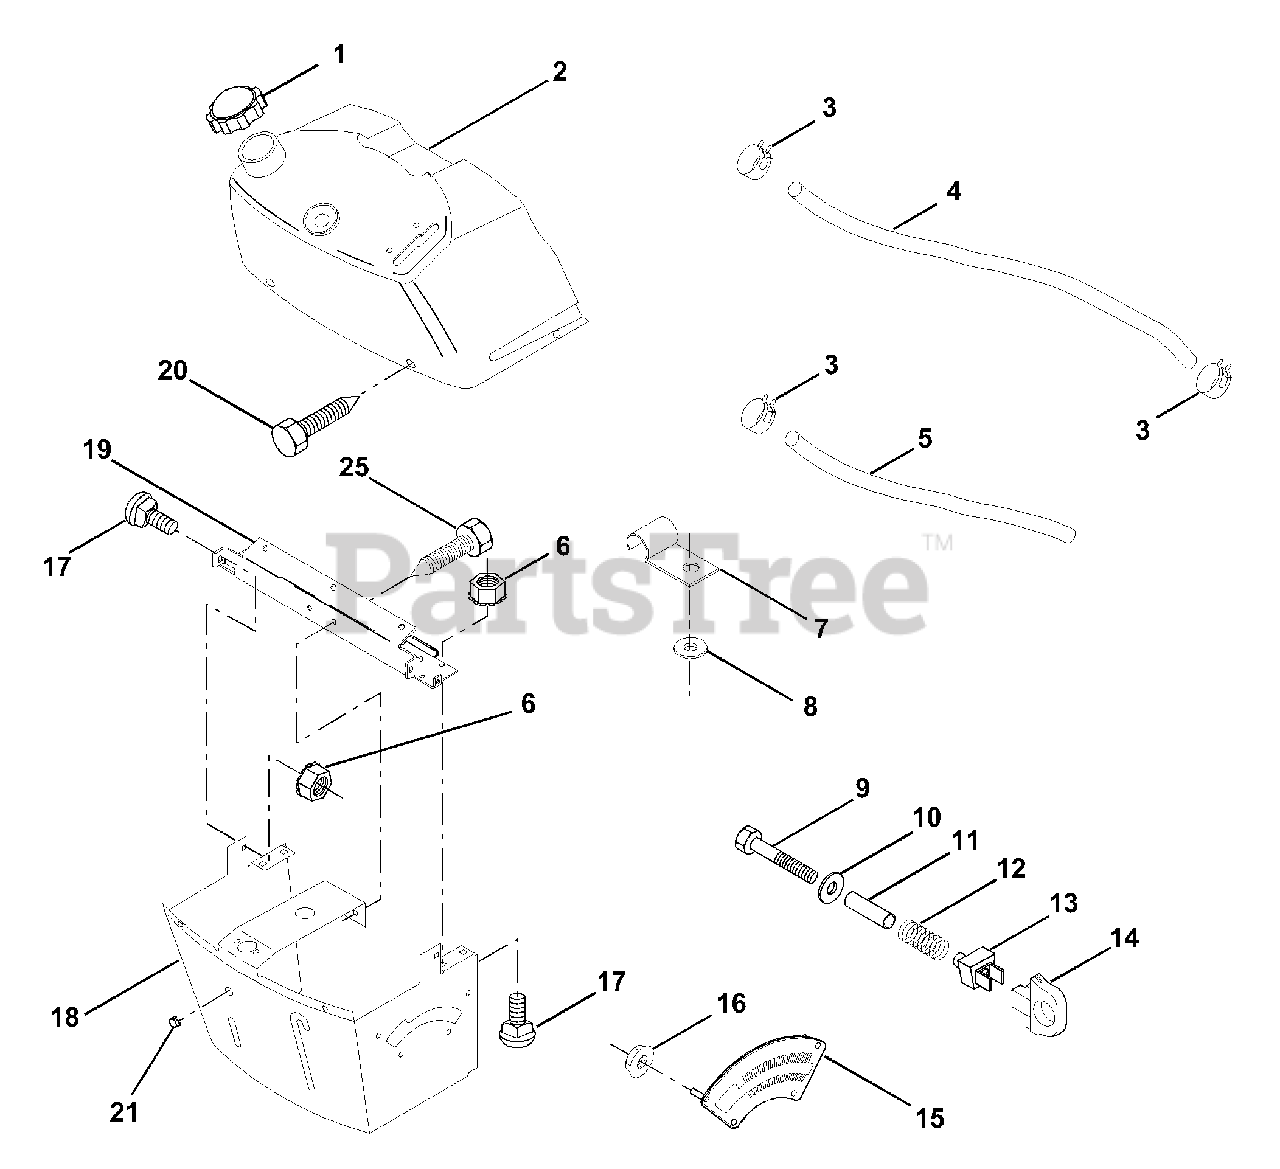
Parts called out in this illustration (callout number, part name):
2	Assembly, Dash & Fuel Tank
3	Clamp, Hose
4	Line, Fuel
5	Line, Fuel
6	Nut, Hex, Keps 1/4-20
7	Clip, Fuel Line
8	Washer 9/32 x 3/4 x 16 Ga.
9	Bolt, Hex, Fin 1/4-20 x 1-3/4
10	Washer 11/32 x 11/16 x 16 Ga.
11	Spacer, Split
13	Clip, Height Adjustment
14	Knob, Height Stop
15	Adjustment, Quadrant Height
16	Nut, Self-Threading 3/16-18
17	Bolt, Carriage 1/4-20 x 1/2 Gr. 5
18	Support Assembly, Dash
19	Brace, Cross
20	Screw, Self-Tapping 1/4-20 x 1/2
21	Plug Dome Black
25	Screw Hex Thd Cut 1/4-20 x 5/8
